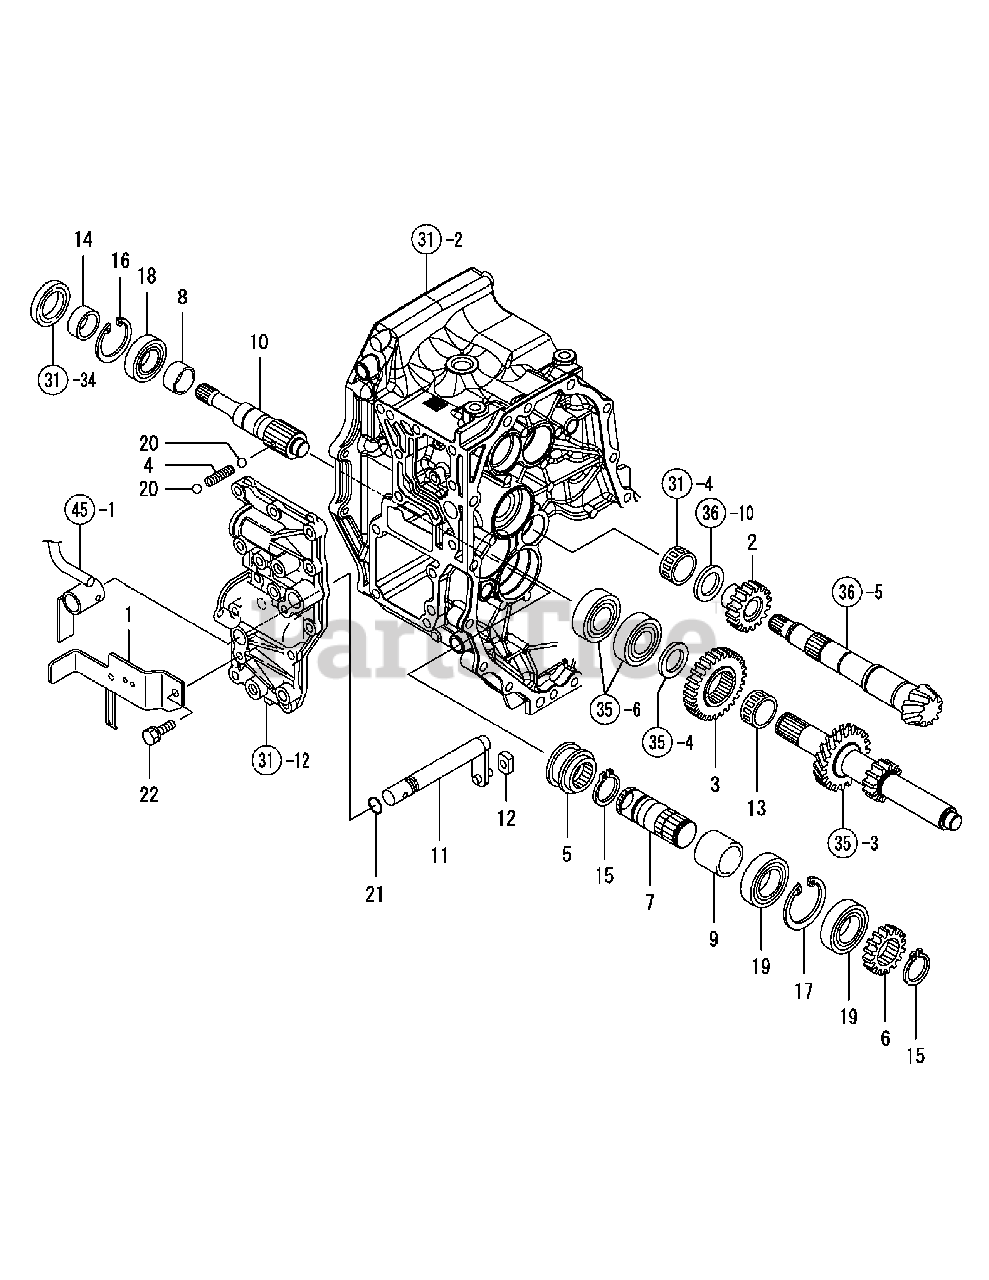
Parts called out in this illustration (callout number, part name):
1	Bracket, 4WD Switch
2	Gear, Drive Mfwd
3	Gear, Idle Mfwd
5	Collar, Shift Front
6	Gear, Driven Mfwd
7	Shaft, Mfwd Drive
8	Collar, 25.4X30X14.8
9	Collar, 30X38X30.7
10	Shaft, Front Drive
11	Arm,Cmp Shift 4WD
13	Bearing, 283516
14	Sleeve Si25X30X13
18	Ball Bearing 6005
20	Ball 1/4, Steel
21	O-Ring 1A P-12.5
